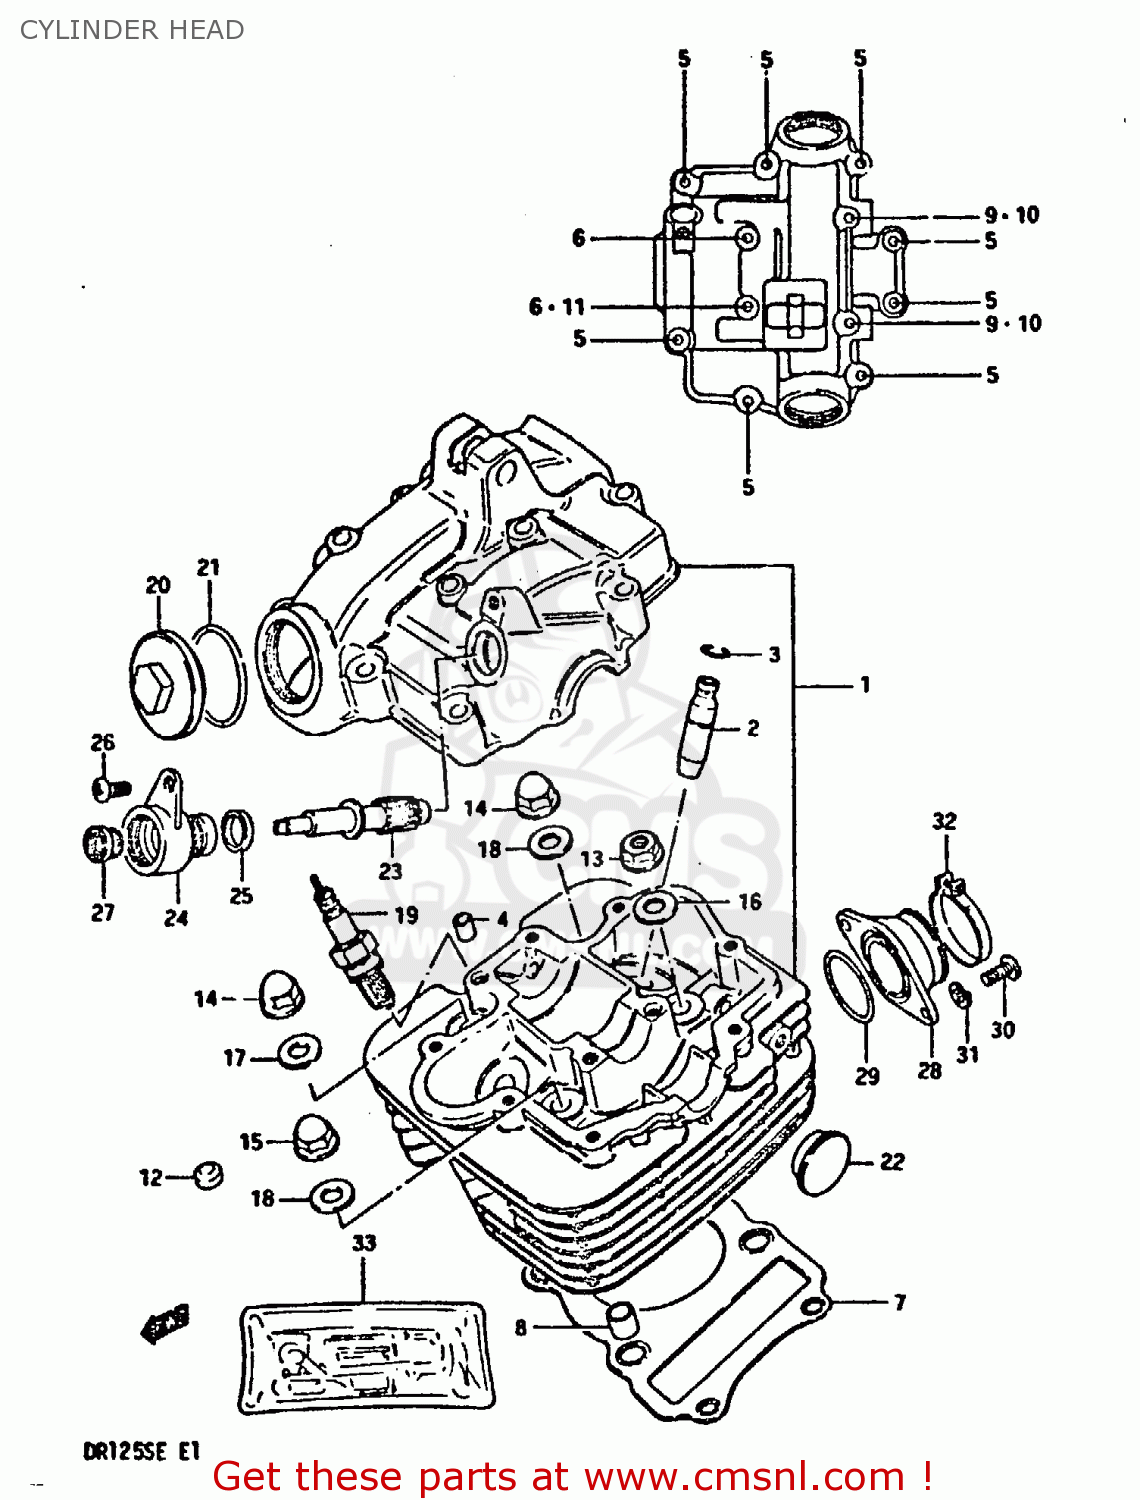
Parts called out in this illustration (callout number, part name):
1	HEAD ASSEMBLY,CYLINDER
2	GUIDE,VALVE
3	RING,SNAP
4	PIN(6.2X8X11)
5	BOLT
6	BOLT ,6X60
7	GASKET,CYLINDER HEAD (NAS)
8	PIN
9	STUD 6X25
10	NUT
11	WASHER
12	PAD,CYLINDER HEAD
13	NUT
14	NUT (8MM)
15	NUT
16	WASHER(8.5X19X2.3)
17	WASHER (8.5X19X2.3)
18	GASKET (NAS)
19	SPARK PLUG
20	CAP,INSPECTION
21	O RING(D:3,ID:29.5)
22	PLUG(OD:22.5)
23	GEAR,TACHOMETER DRIVEN
24	SLEEVE,TACHOMETER DRIVE GEAR
25	SEAL,TACHOMETER DRIVEN
26	SCREW
27	SEAL,OIL(5X12X8)
28	PIPE,INTAKE
29	O RING(D:2.4,ID:31.7)
30	SCREW
31	LOCK WASHER
32	CLAMP
33	GASKET SET
